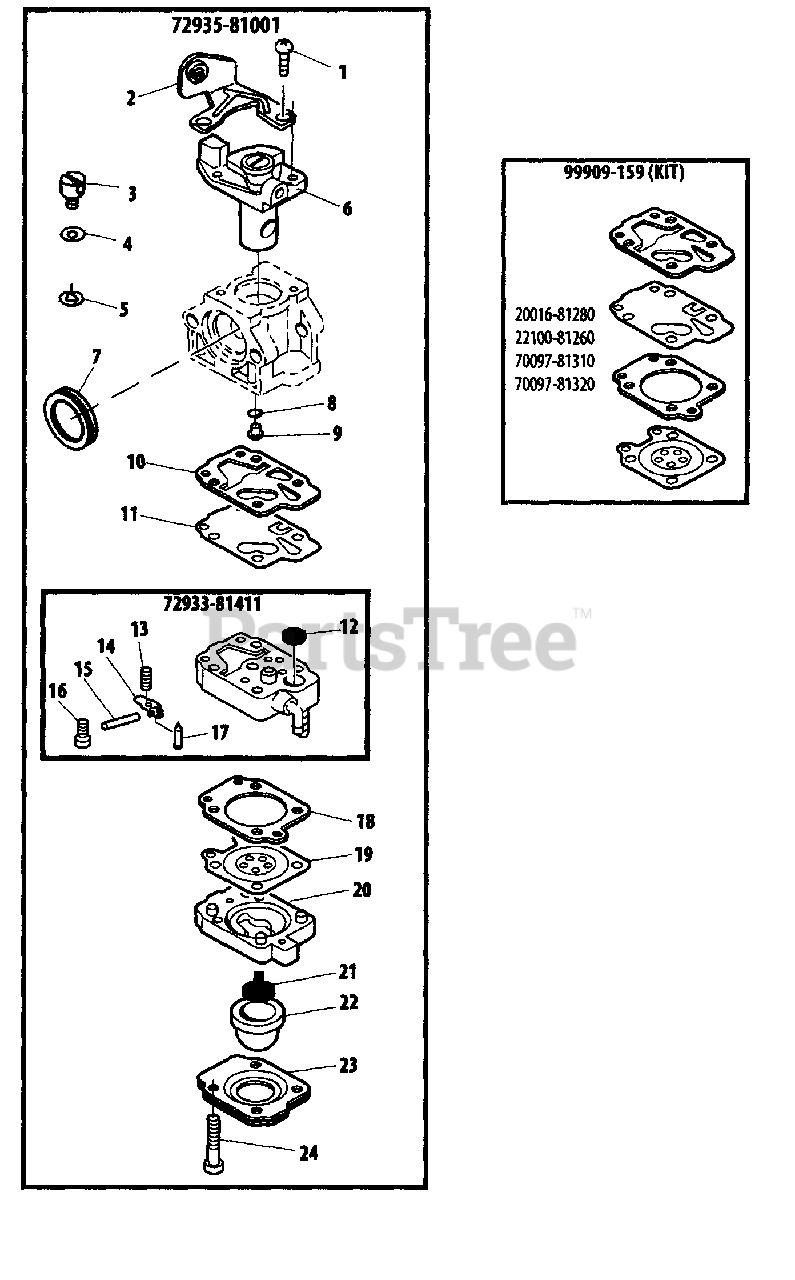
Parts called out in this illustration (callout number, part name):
1	SCREW
2	BRACKET, CABLE
3	SWIVEL
4	WASHER
5	RING, RETAINING
6	THROTTLE VALVE ASSY
7	SEAL
8	O-RING
9	JET
10	GASKET, PUMP
11	DIAPHRAGM, PUMP
12	STRAINER
13	SPRING, METERING LEVER
14	LEVER, METERING
15	PIN, METERING LEVER
16	SCREW, METERING LEVER PIN
17	VALVE, INLET NEEDLE
18	GASKET, METERING
19	DIAPHRAGM, METERING
20	BASE, PURGE
21	VALVE, CHECK
22	BULB, PURGE
23	RETAINER, PURGE BULB
24	SCREW, PUMP COVER
72933-81411	BASE, PURGE
72935-81001	CARBURETOR
99909-159	DIAPHRAGM/GASKET KIT
